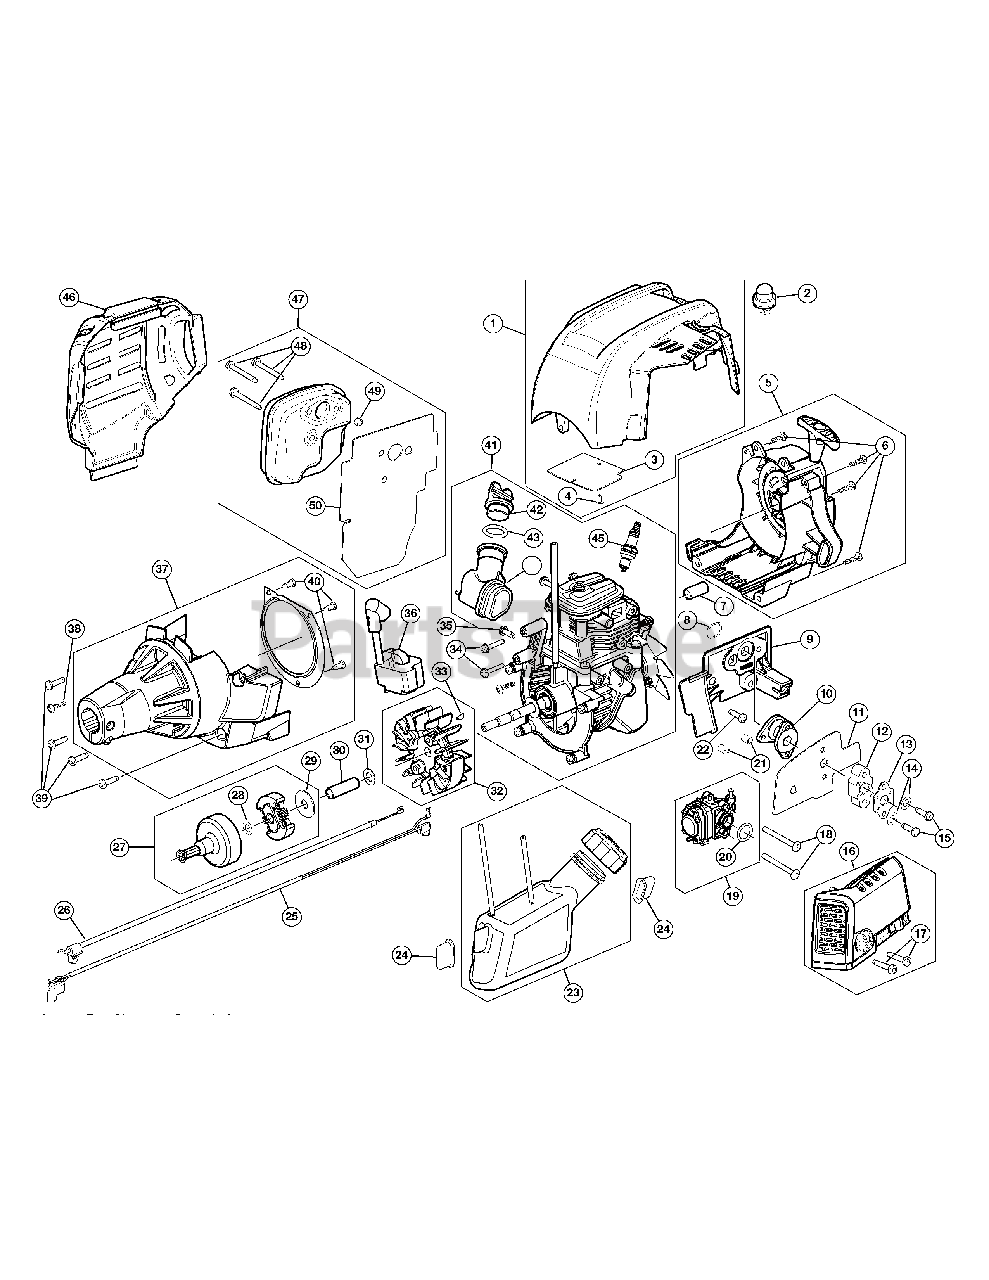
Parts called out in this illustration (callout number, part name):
1	Top Housing Assembly
2	Air Purge Primer
3	Top Cover Gasket
5	Starter Housing Assembly
7	Electric Start Adapter
9	Intake Port
10	Boot Assembly
11	Carburetor Gasket
12	Insulator
13	Insulator Gasket
15	Screw
16	Aircleaner Assembly
19	Carburetor Assembly
21	Aircleaner Spacer
22	Screw
23	Fuel Tank Assembly
24	Fuel Tank Pad
25	Lead Wire
26	Thottle Cable
27	Clutch Assembly
28	Thrust Washer
29	Clutch Washer
30	Power Shaft Spacer
31	Thrust Washer
32	Flywheel Assembly
35	Screw
36	Module Assembly
37	Clutch Cover Assembly
41	Shortblock Assembly
42	Oil Fill Plug
44	Oil Fill Tube
45	Spark Plug
46	Muffler Housing
47	Muffler Assembly
48	Screw
49	Aircleaner Spacer
50	Muffler Gasket
